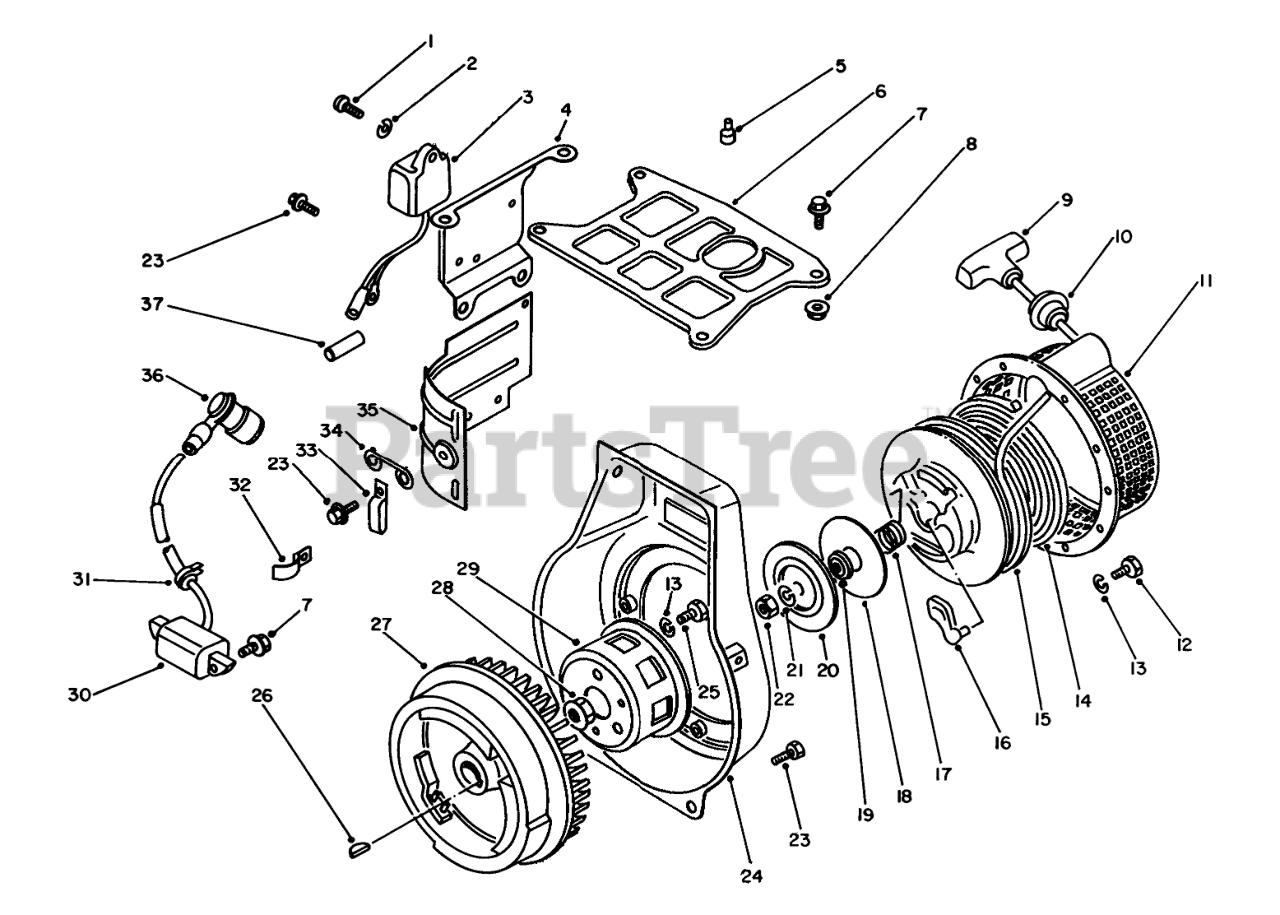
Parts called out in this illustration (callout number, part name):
1	Screw
2	Washer
3	Transistor Magnet
4	Bracket
5	Cushion
6	Cowling-Upper
8	M6 X 1 LOCKNUT
9	Grip
10	Grip Assembly (Incl. Ref. #9)
11	Starter Assembly (Incl. Ref. #14-22)
13	Lockwasher
14	SPRING
16	Ratchet
17	Spring
18	Plate-Slide
19	Cover
20	Plate
21	WASHER-LOCK
24	COVER
27	ROTOR ASM
29	STARTER PULLEY
30	STARTER ASM
31	Grommet
32	Clamp
33	Clamp
34	CLAMP
35	COWLING
36	Cap-Spark Plug
